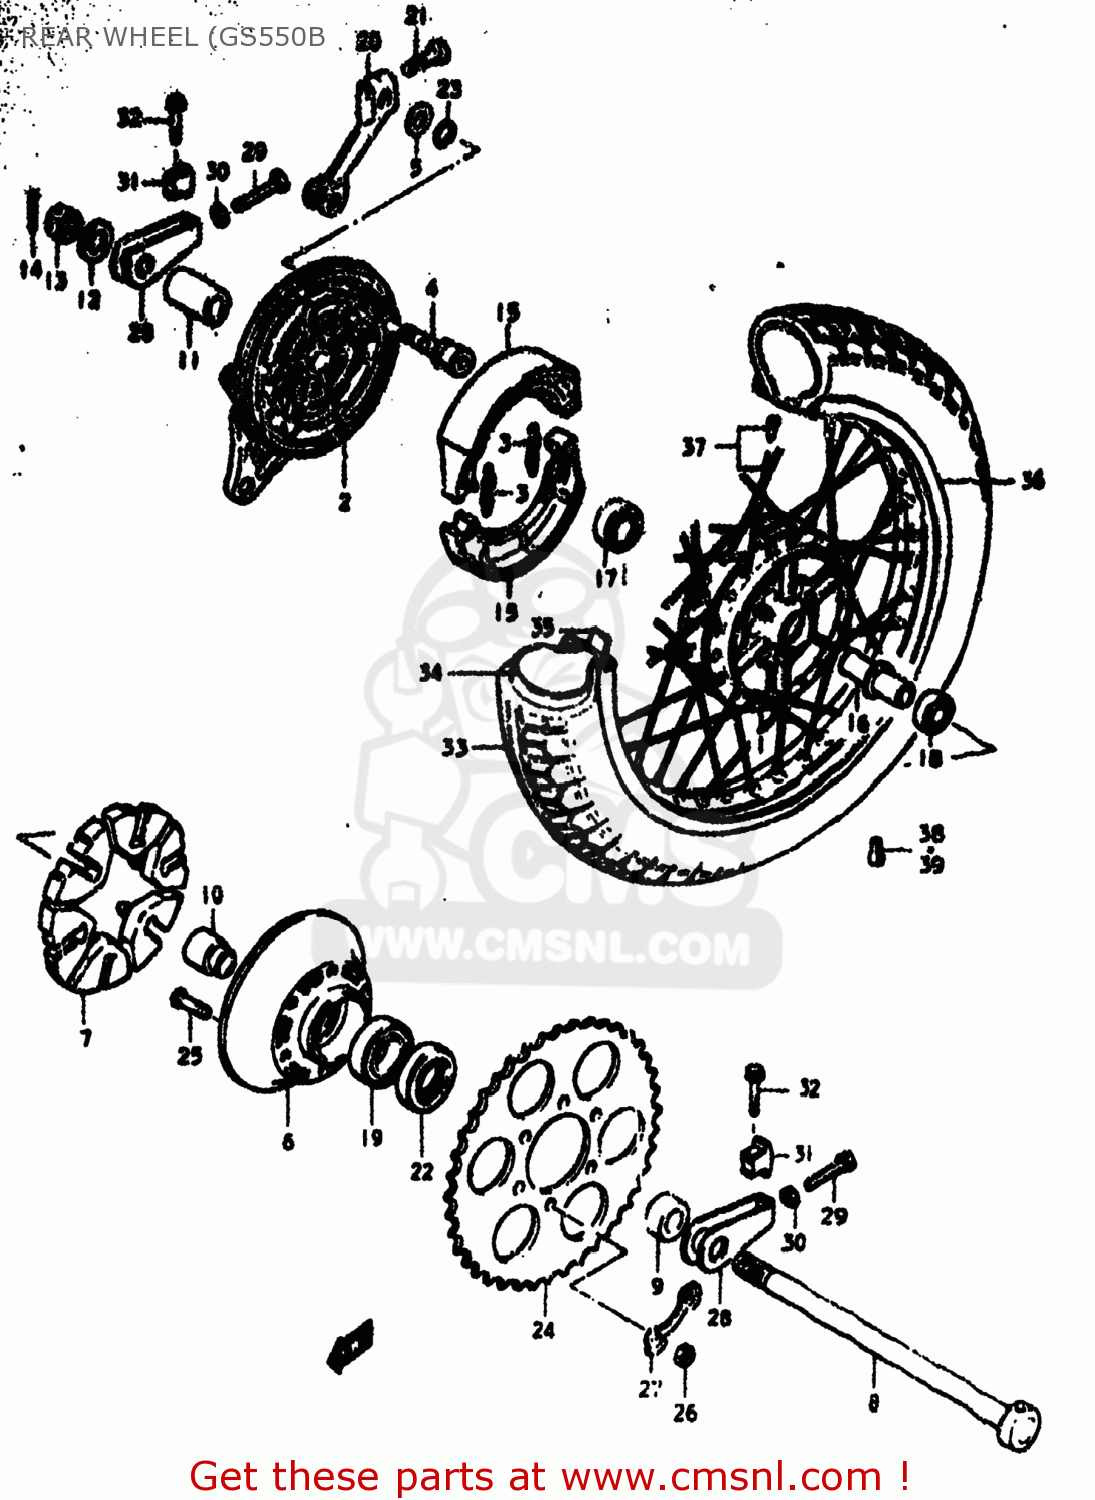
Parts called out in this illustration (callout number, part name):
1	DRUM,REAR HUB
2	PANEL,REAR HUB
3	SPRING,BRAKE SHOE
4	CAM,FRONT BRAKE
5	WASHER (15X24X1.6)
6	DRUM,REAR SPROCKET MOUNT
7	CUSHION,REAR DRUM
8	AXLE,REAR
9	SPACER (17.5X28X51.8)
10	SPACER,REAR HUB BEARING
11	SPACER(17X30.5X22.3)
12	WASHER (17X30X3.2)
13	NUT
14	PIN,COTTER
15	SHOE,BRAKE
16	SPACER
17	BEARING
18	BEARING
19	BEARING
20	LEVER,REAR BRAKE CAM
21	BOLT
22	OIL SEAL
23	O-RING,BOSS
24	SPROCKET,REAR
25	BOLT
26	NUT
27	WASHER
28	ADJUSTER,CHAIN
29	BOLT
30	NUT
31	SUPPORTER,CHAIN ADJUST
32	BOLT
33	TIRE
34	TUBE ASSEMBLY,WHEEL,INNER
35	PROTECTOR,WHEEL,INNER
36	RIM,WHEEL
37	SPOKE SET,REAR
38	BALANCER,WHEEL (B)
39	BALANCER,WHEEL (30G)
